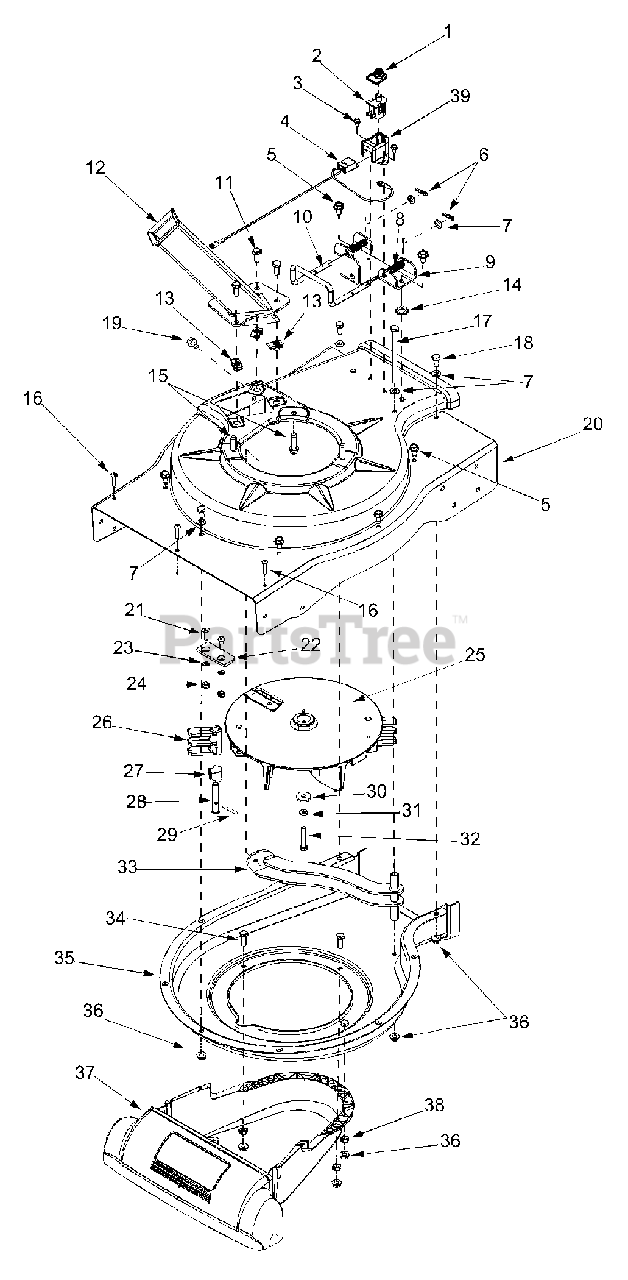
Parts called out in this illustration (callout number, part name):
1	Switch Cover
2	Safety Switch
3	Hex Washer Screw #10-16 x.50
4	Wire Harness
5	Hex Washer Screw 5/16-18 x.625
6	Cotter Pin
7	Flat Washer.330 ID x.630 OD
8	Compression Spring
10	Lock Rod
11	Hex Cap Screw 5/16-18 x.75
13	U-Clip Lock Nut 5/16-18
14	External Lock Washer 5/16
15	Hex Washer Screw 3/8-16 x 1.25
16	Screw #12-16 x 1.0
17	Hex Cap Screw 5/16-18 x 4.5
18	Hex Cap Screw 5/16-18 x.625
19	Hex Washer Screw 5/16-18 x.625
22	Chipper Blade
23	Lock Washer 5/16
24	Hex Lock Nut 5/16-24
25	Impeller Assembly
26	Flail Blade
27	Pin Clip
28	Clevis Pin
29	Spiral Pin
30	Flat Washer.375 ID x 1.25 OD
31	Lock Washer 3/8
32	Hex Cap Screw 3/8-24 x 2.0
34	Hex Cap Screw 5/16-18 x.875
36	Lock Nut 5/16-18
37	Nozzle Cover
38	Lock Nut 5/16-18
39	Safety Switch Cover
